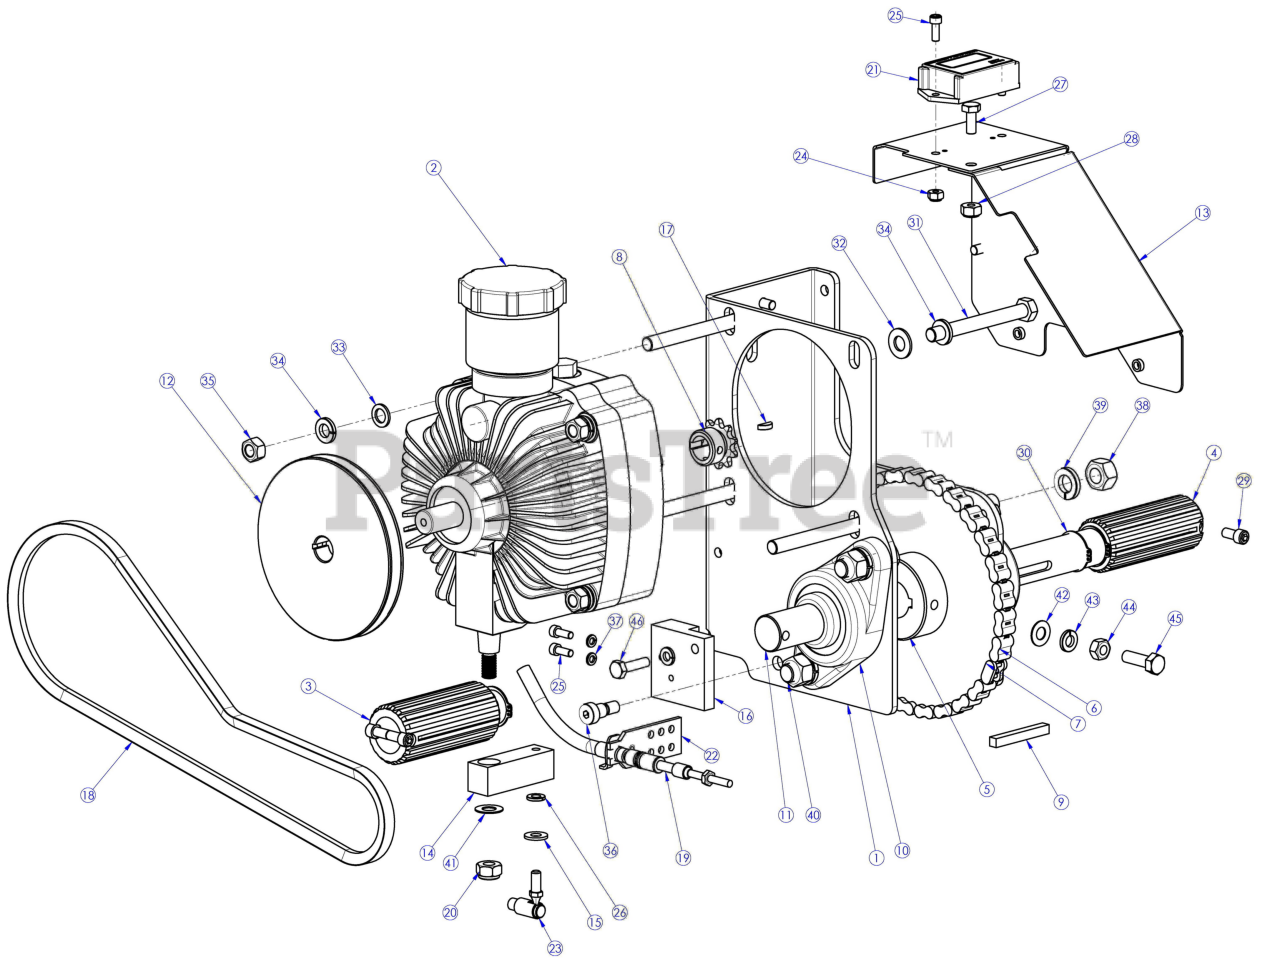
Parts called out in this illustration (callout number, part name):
1	Frame, Pump
2	Hydrostatic Pump
3	Tube, Driver, Right
4	Tube, Driver, Left
5	Sprocket, 54-Tooth
6	Chain, Roller #35
7	Connecting Link #35
8	Sprocket, 10T
9	Key, 1/4 X 1/4 X 2.00
10	Bearing, Flange, 1" Id
11	Drive Shaft
12	Sheave, 1/3V 5.00 Od X 17Mm Id
13	Cover, Pump Assembly
14	Arm, Speed Control
15	Washer, 1/4" Flat S.S.
16	Block, Cable Mount
17	Key, Woodruff, #3
18	Belt, 3L345
19	Cable, Speed Control
20	Nut, Nyloc, 3/8-16
21	Tachometer/Hour Meter
22	Cable Bracket
23	Fitting, Ball Joint
24	Nut, Nyloc, #10-32 S.S.
25	Shcs 10-32 X 1/2 S.S.
26	Washer, Split 1/4" S.S.
27	HHB 1/4-20 X .625 S.S.
28	Nut, Nyloc, 1/4-20 Cad
29	Shcs 1/4-20 X 1/2 S.S.
30	Snap Ring, Ext 1.000"
31	HHB 3/8-16 X 3.5
32	Washer, 3/8" Flat
33	Washer, 3/8"X .06"Thk Flat S.S.
34	Washer, Split 3/8" S.S.
35	Nut, 3/8-16 Hex, Gr5 Zinc
36	Shsb, 3/8 X 3/8
37	Washer, Split #10 S.S.
38	Nut, 1/2-13 Hex, Gr5 Zinc
39	Washer, Split 1/2" S.S.
40	HHB 1/2-13 X 1 1/2
41	Washer, 3/8"X .030"Thk Flat
42	Washer, 5/16" Flat S.S.
43	Washer, Split 5/16" S.S.
44	Nut, 5/16-18 Hex, S.S.
45	HHB 5/16-18 X 1
46	HHB 1/4-20 X 1 S.S.
